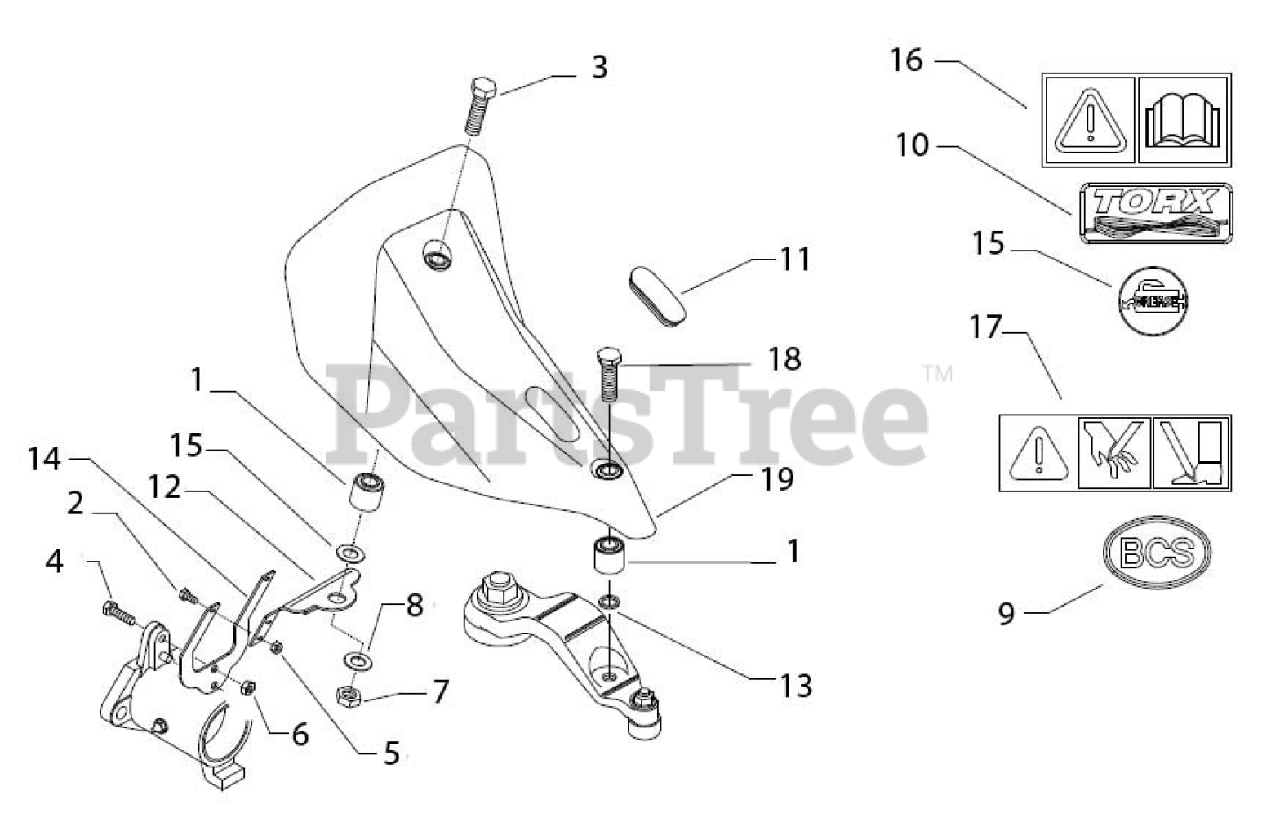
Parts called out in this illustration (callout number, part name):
1	SILENT-BLOCK
5	HEXNUT SELFLOCK NUT, M6
6	HEXNUT SELFLOCK NUT, M8
7	SELFLOCK NUT, M14 LOW
8	SPRING WASHER
18	SCREW SPECIAL
19	FRONT DEFLECTOR
